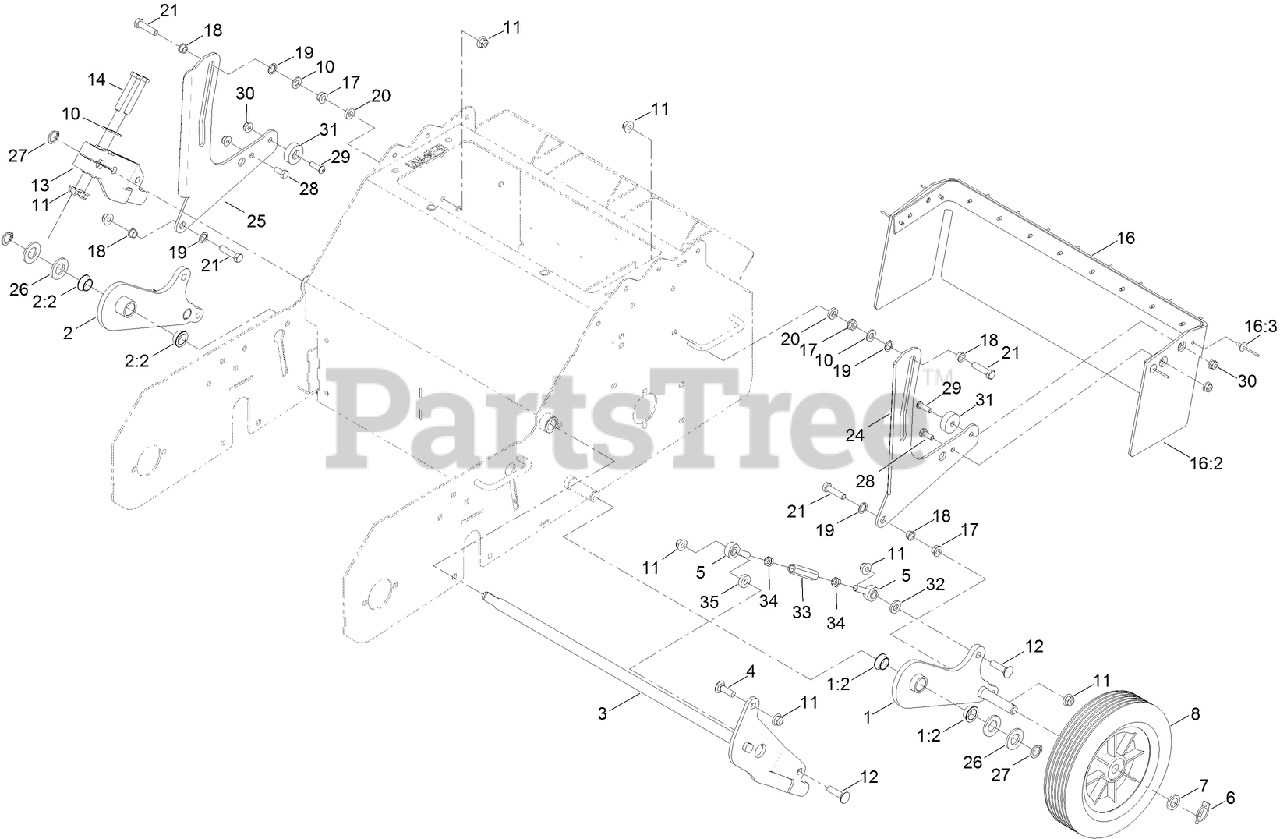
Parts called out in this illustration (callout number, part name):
1	WHEEL ARM ASM-LH W/BRGS
1:2	BUSHING-BRONZE
2	WHEEL ARM ASM-RH W/BRGS
2:2	BUSHING-BRONZE
3	SHAFT-PIVOT
4	BOLT-CARR
5	BALLJOINT
6	PIN-KLIK
7	SPACER-BEARING
8	WHEEL-TRANSPORT 10"
10	WASHER-FLAT
11	NUT-HF, NI
12	SCREW-CARR
13	ARM-LIFT, RH
14	SCREW-HH
16	GUARD-FOOT
16:2	FOOT-SHIELD
16:3	RIVET-POP
17	NUT-HHF, WHIZ
18	BUSHING-FLANGED
19	WASHER-NYLON
20	SPACER
21	SCREW-HH
24	GUARD-ARM, LH
25	GUARD-ARM, RH
26	WASHER-FLAT
27	RING-RETAINING
28	SCREW-HH
29	SCREW-HSH
30	NUT-HF, NI
31	GUIDE-ARM, TRAIL
32	WASHER
33	ROD-LIFT LINK
34	NUT-HJ
35	SPACER
